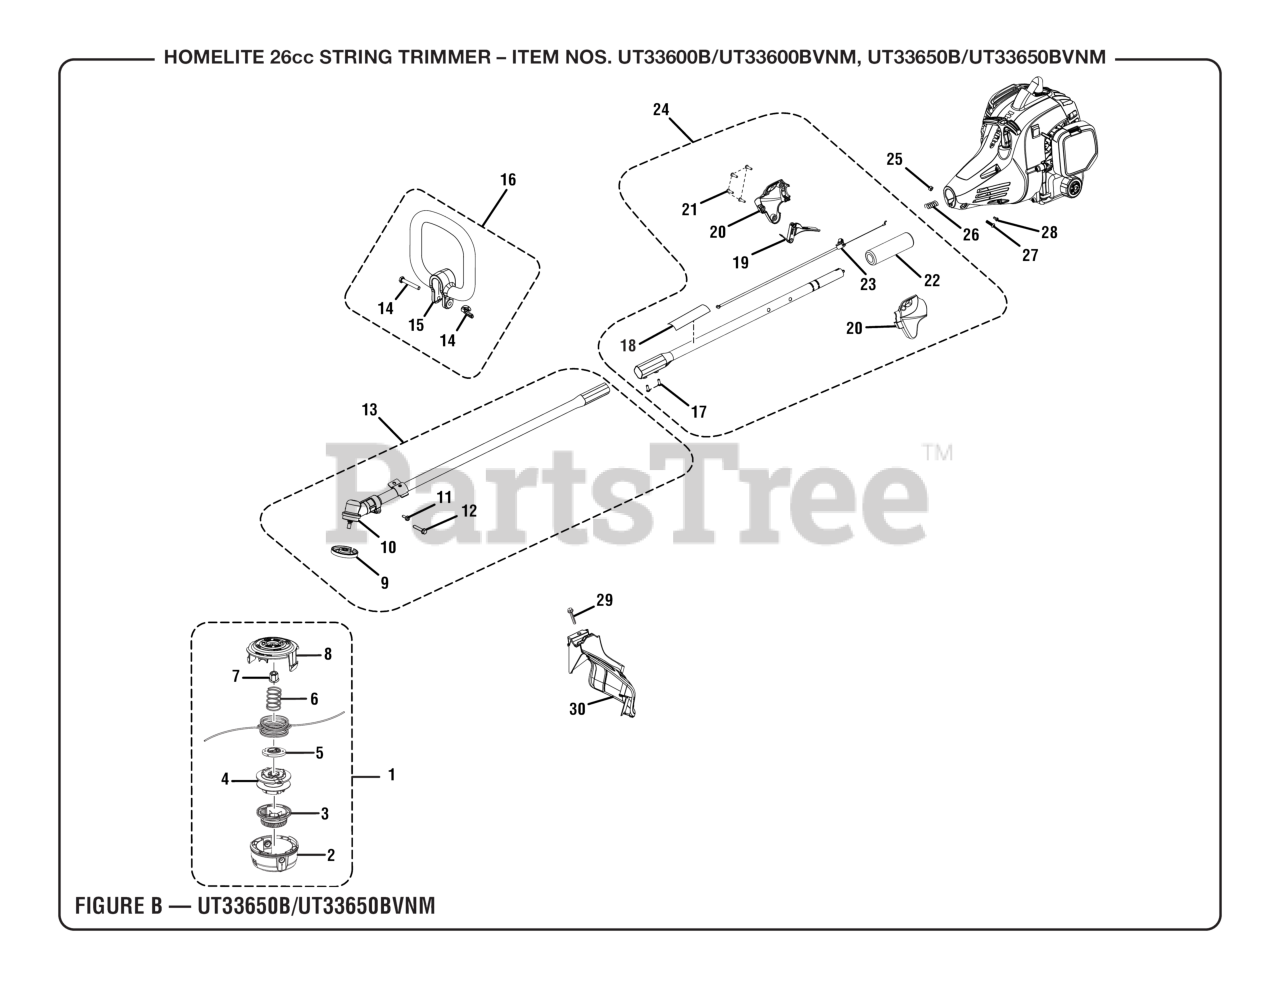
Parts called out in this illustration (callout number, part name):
1	Trimmer Head Assembly
2	Lower Housing
3	Bump Knob (Gray)
4	Spool Assembly
5	String Guide
6	Compression Spring
7	Hex Nut (M8, Left Hand Threads)
8	Upper Housing
9	Flanged Washer
10	Gear Case Assembly
11	Screw w/Washer (10-24 x 5/8 in., Hex Hd. T.F.)
12	Screw (1/4-20 x 1-1/4 in., Hex Washer Hd. S.T.)
13	Lower Boom Assembly
14	Fastener Parts Kit
15	Front Handle
16	Front Handle Assembly
17	Set Screw (M5 x 10 mm, Hex Soc. Hd.)
18	Icon Warning Label
19	Throttle Trigger
20	Trigger Handle Assembly
21	Screw (M4 x 20 mm, T20 Torx Pan Hd. T.Fl.)
22	Rubber Grip
23	Throttle Cable
24	Boom Assembly
25	Hex Nut (M6.3 x 1)
26	Compression Spring
27	Screw (M6 x 20 mm, T27 Torx Button Hd.)
28	Screw (M4 x 8 mm, T25 Torx Pan Hd. T.F.)
29	SCREW (#1/4-20 X 1-1/4 in. HEX WASHER HD.)
30	Grass Deflector Assembly
